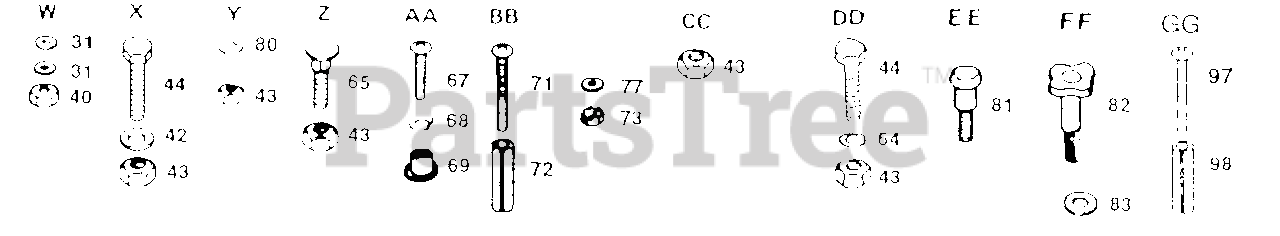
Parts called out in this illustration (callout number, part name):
31	Washer 9/32 x 3/4 x 16 Ga.
40	Nut-Hex 1/4-20
42	Washer 13/32 x 13/16 x 12 Ga.
43	Nut-Crownlock 3/8-16
44	Bolt-Hex 3/8-16 x 1
64	Washer 13/32 x 1-1/4 x 12 Ga.
65	Bolt-Carriage 3/8-16 x 3/4
67	Screw-Cross Recess Pan Hd. Mach. 10-24 x 1/2
68	Washer-Lock No. 10
69	Nut-Weld
71	Screw-Machine Cross Recess 10-24 x 1-1/4
72	Spacer-Split 10 x 3/4
73	Nut-Keps 10-24
77	Washer 7/32 x 1/2 x 18 Ga.
80	Washer 13/32 x 1 x 14 Ga.
81	Shoulder - Bolt 5/16 x 18 UNC
82	Knob - 1/2
83	Washer 17/32 x 13/16 x 12 Ga.
97	Bolt, 1/4 - 20 x 2 1/2
